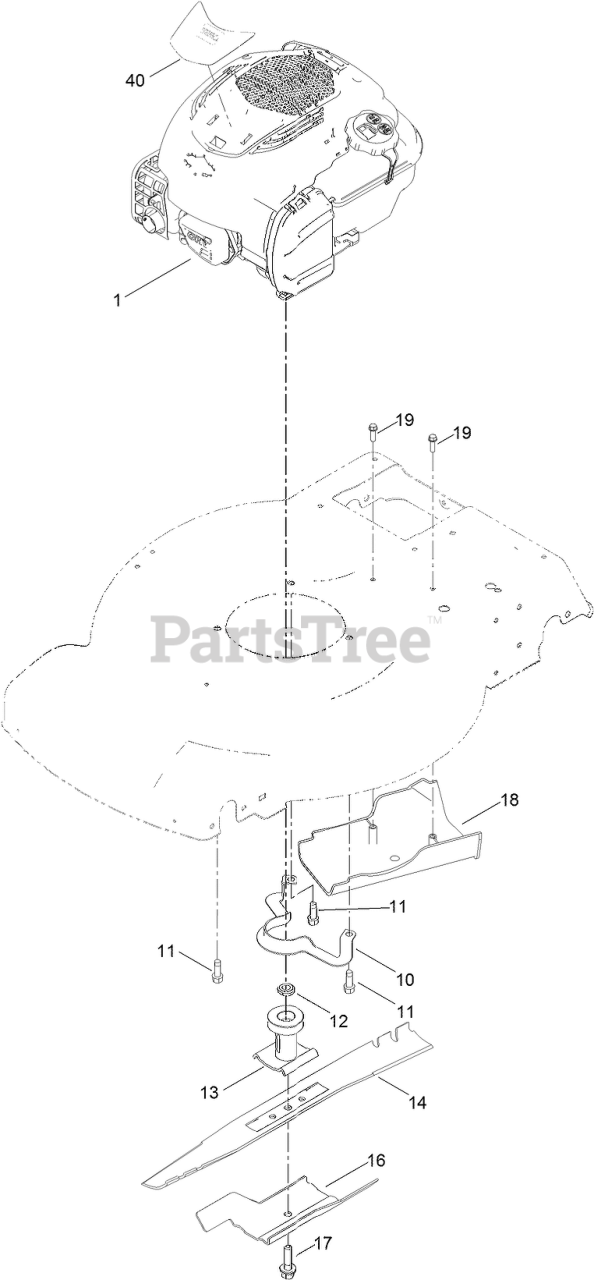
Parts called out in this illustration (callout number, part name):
10	GUIDE-BELT
11	SCREW-TAPTITE
12	SPACER-DRIVER
13	DRIVER-BLADE
16	ACCELERATOR-BLADE
17	BOLT-BLADE
18	COVER-BELT
19	SCREW-PLASTITE, HWH
40	DECAL-SHROUD
